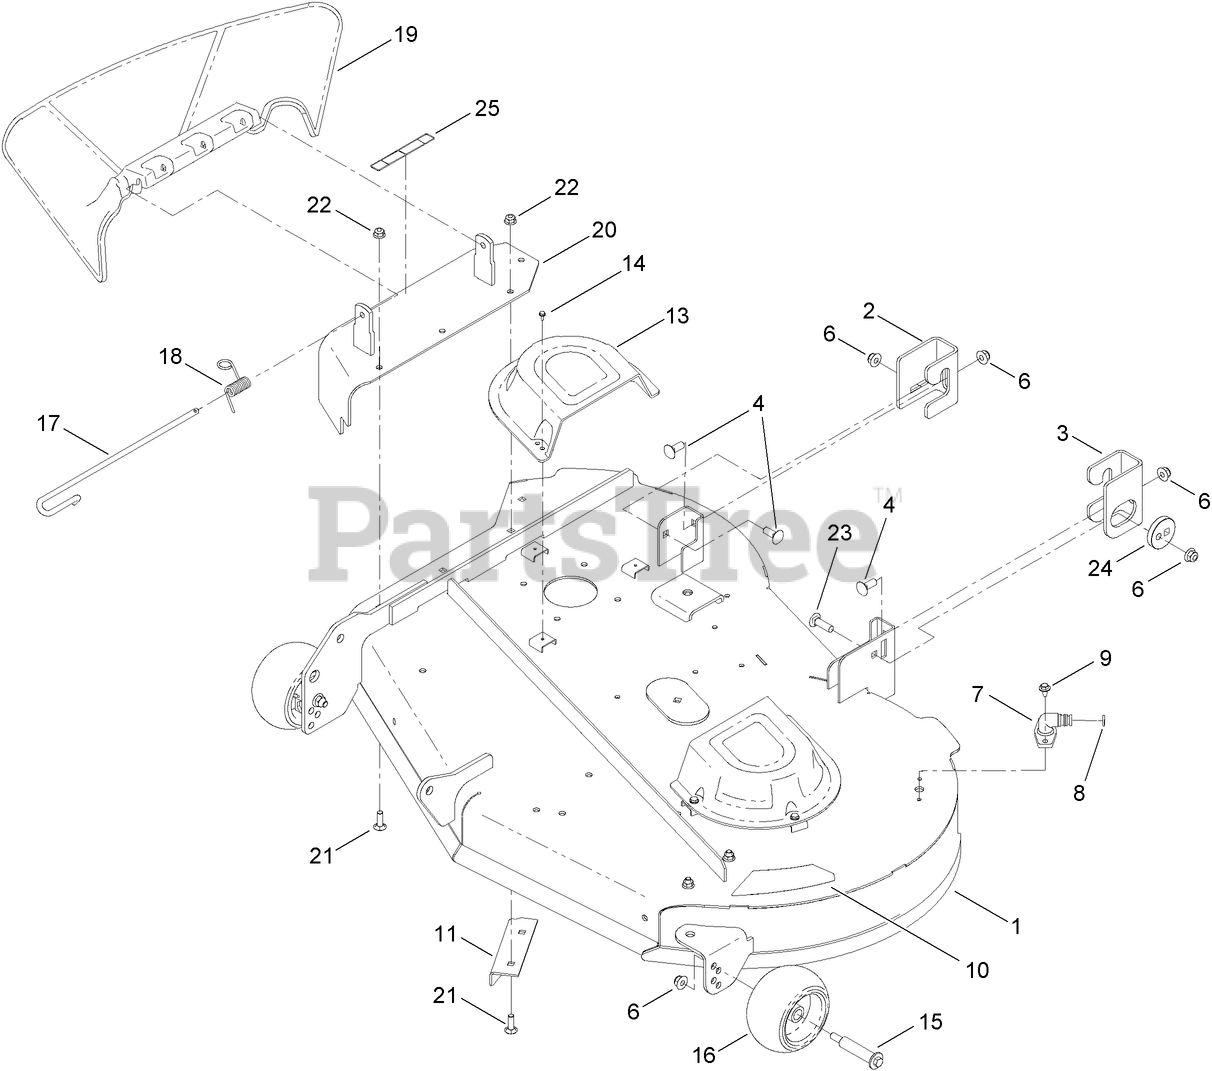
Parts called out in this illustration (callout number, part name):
1	42 INCH DECK AND DECAL ASM
3	BRACKET-HANGER, LH
4	BOLT-CARR
6	NUT-HF, NI
8	O-RING
9	SCREW-HHFTF
10	DECAL-DECK
11	BAFFLE-CUTOFF
13	COVER-BELT
14	SCREW-TAPTITE
15	BOLT-SHOULDER
16	ROLLER-SCALP, ANTI
17	PIN-CHUTE
18	SPRING-TORSION
19	DEFLECTOR-DISCHARGE
20	DISCHARGE COVER ASM
21	SCREW-CARR
22	NUT-HF, NI
23	SCREW-CARR
24	ECCENTRIC
25	DECAL-DANGER
